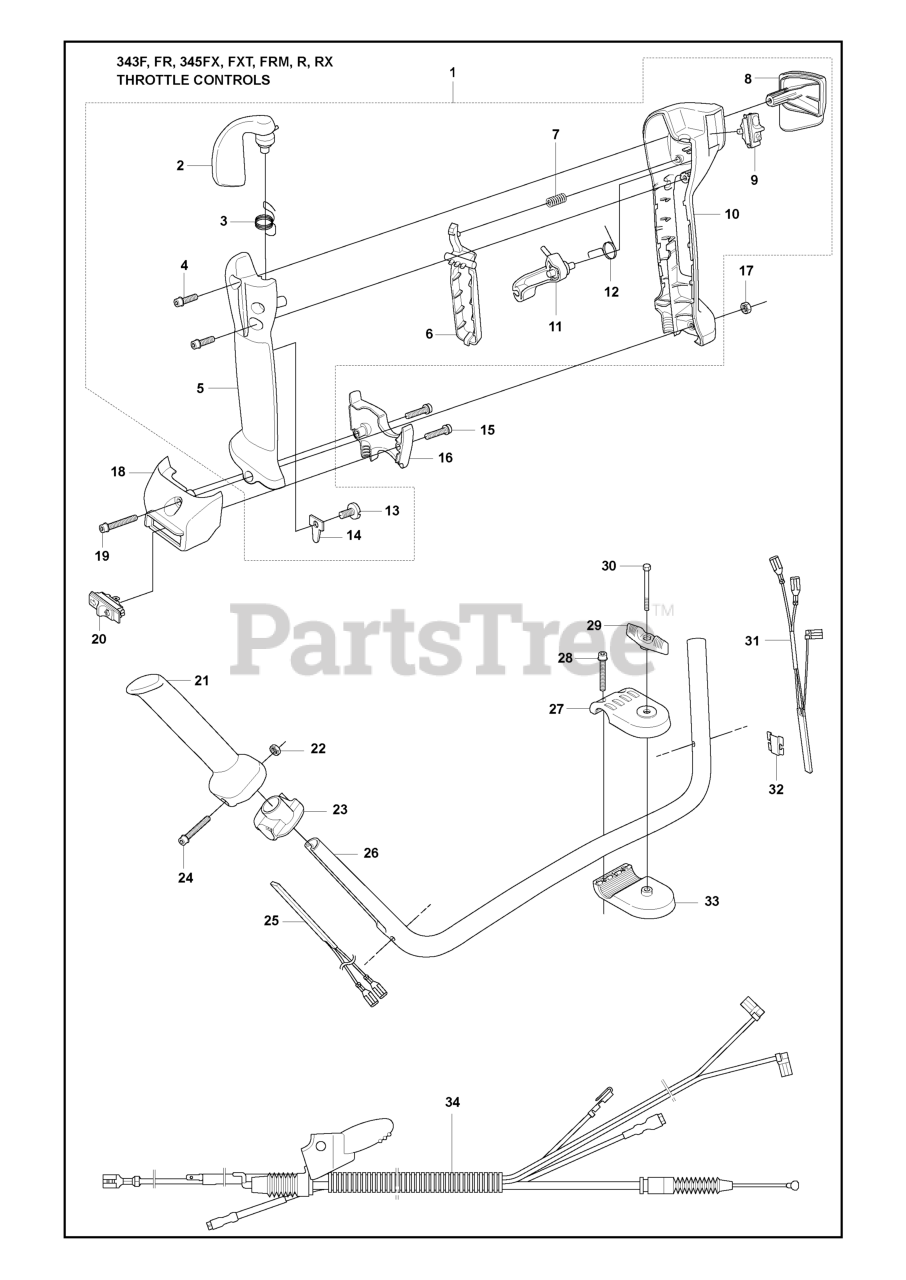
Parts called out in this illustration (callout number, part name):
1	THROTTLE HANDLE
2	THROTTLE TRIGGER
3	RP SPRING
5	HANDLE
6	THROTTLE LOCK
9	STOP BUTTON
10	HANDLE
15	SCREW
16	HOLDER
17	NUT M6M M5
18	HOLDER
19	SCREW
20	SWITCH (G)
21	HANDLE
22	NUT M6M M5
25	HEATING ELEMENT
26	RP HANDLE
26	%HANDLE
27	HANDLE BRACKET
30	%SCREW
31	HEATING ELEMENT
32	HOLDER
33	HANDLE HOLDER LOWER
34	RP WIRING ASSY
34	WIRING ASSY
